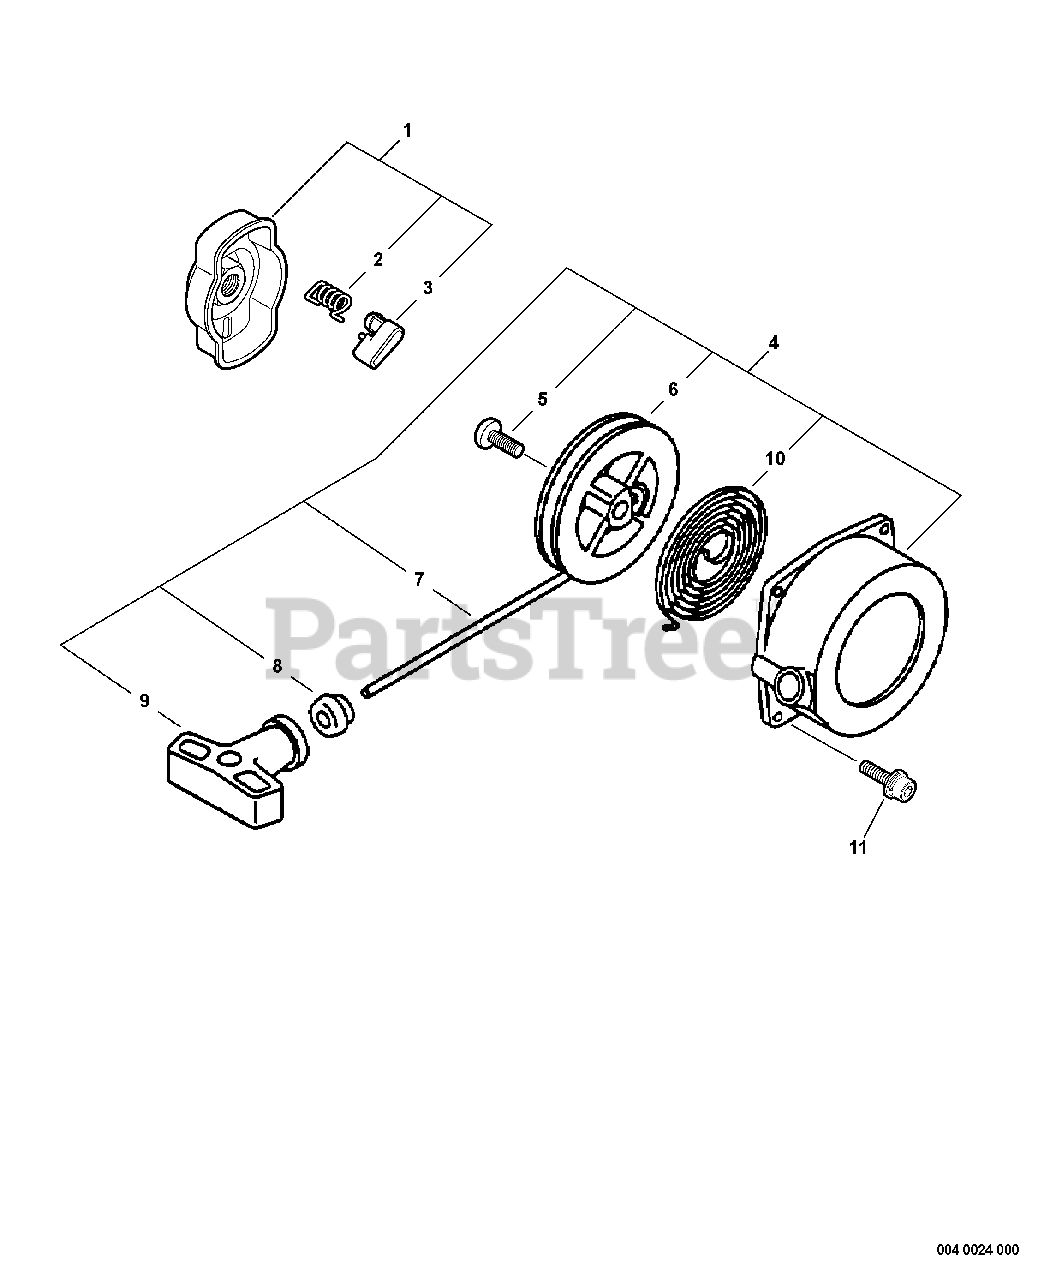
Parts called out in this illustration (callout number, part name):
1	STARTER PAWL ASSY
2	SPRING, RETURN
3	PAWL, STARTER - BLACK
4	STARTER ASSY
6	REEL, ROPE
7	ROPE, STARTER - 3.5X960
8	GUIDE, ROPE
9	GRIP, STARTER
10	SPRING, REWIND
11	SCREW - 4X16
